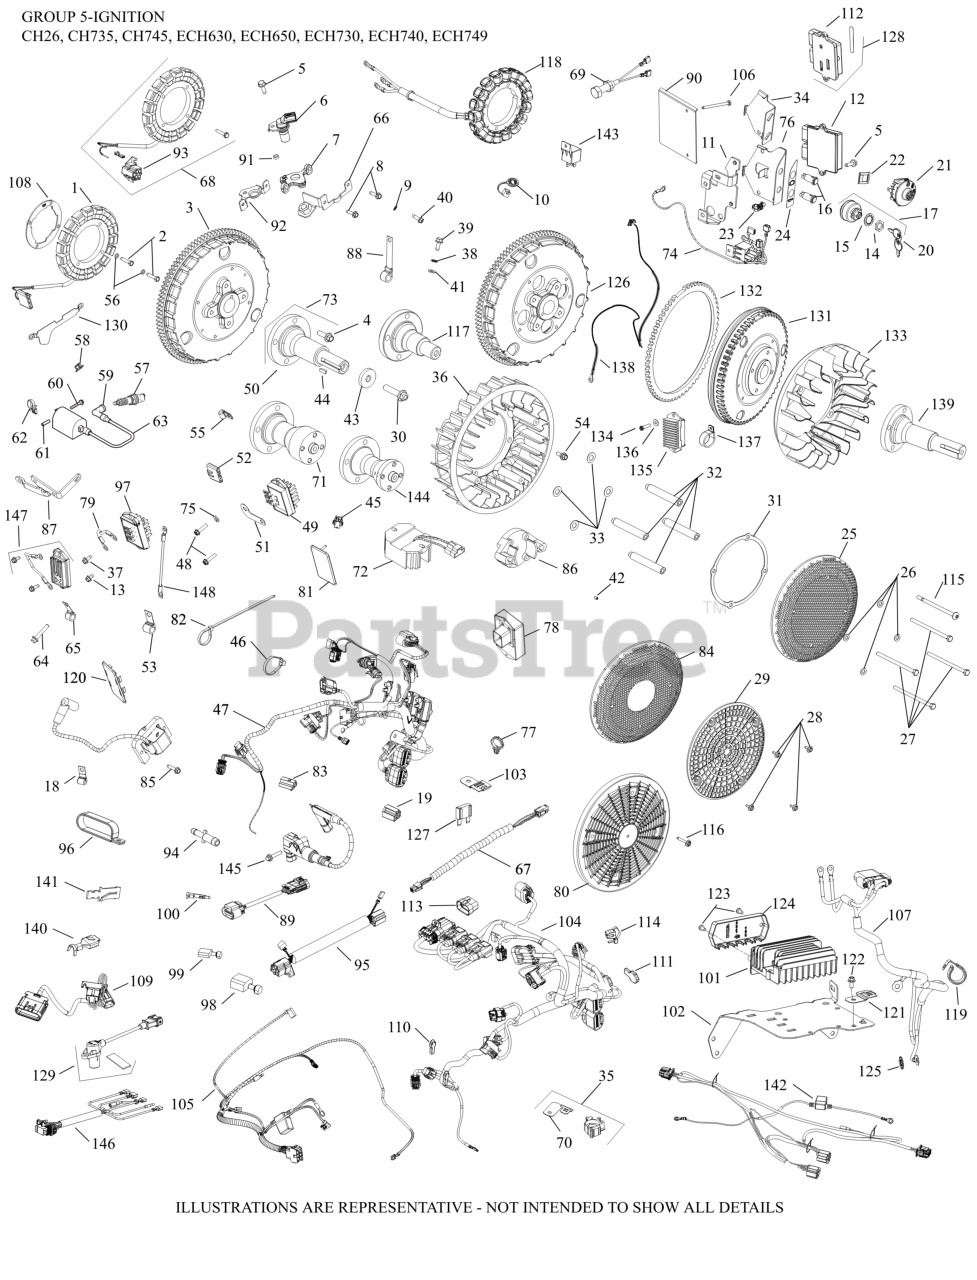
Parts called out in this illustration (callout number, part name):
1	KIT, 15 / 20 AMP STATOR
2	SCREW, THREAD FORMING
3	FLYWHEEL, ASSEMBLY
6	SENSOR, SPEED
8	SCREW, THREAD FORMING
9	WASHER, INT TOOTH LOCK #10
11	BRACKET, ECU
23	TIE, WIRE
36	FAN-USE 24 755 253-S
37	SCREW, THREAD FORMING
38	WASHER, INT TOOTH LOCK 1/4"
41	WASHER, FLAT 1/4" (O.D. 1/2")
42	SCREW, HEX FLANGE
43	WASHER, FLAT
44	KEY, 3/16" X 5/8"
48	SCREW, HEX FLANGE HI-LO
52	CONNECTOR
54	BOLT, SHOULDER
57	PLUG, SPARK (STD)
63	COIL, IGNITION - EFI
77	RETAINER, WIRE HARNESS
92	BRACKET, SENSOR
97	REGULATOR, RECTIFIER (20-30AMP,FW W/OVP)
104	HARNESS, WIRING (B-BAY, EFI-ETB)
113	CAP, DIAGNOSTIC (8-WAY)
114	TIE, WIRE EDGE FIXED
128	MODULE, ECU MT05.3 SERVICE
145	SCREW, HEX FLANGE
